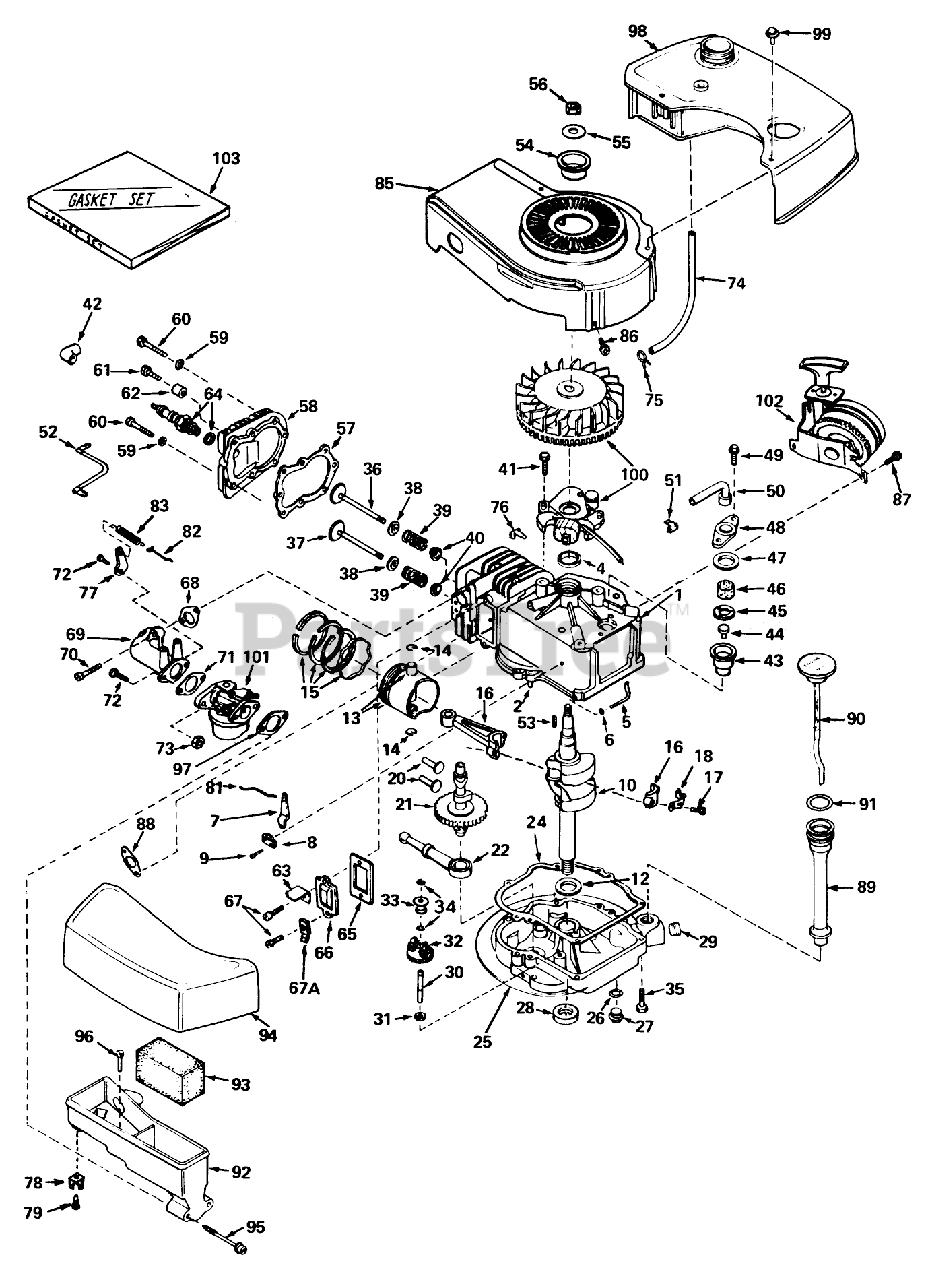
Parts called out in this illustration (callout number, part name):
1	Cylinder Assembly (Incl. Nos. 2, 4 87)
2	Pin-Dowel
4	Seal-Oil
5	Rod, Governor (Incl. No. 36)
6	Washer-Flat
7	Governor Lever
8	Clamp-Lever, Governor
9	Screw
10	Crankshaft
12	Washer-Thrust
13	Piston Pin Assembly (Incl. 2 of No. 14)(Std.)
13	Piston Pin Assembly (Incl. 2 of No. 14)(.010 Oversize)
13	Piston Pin Assembly (Incl. 2 of No. 14)(.020 Oversize)
14	Ring-Retaining, Piston Pin
15	Ring Set-Piston Std.
15	Ring Set-Piston .010 oversize
15	Ring Set-Piston .020 oversize
16	Rod Assembly, Connecting (Incl. Nos. 17 18)
17	Connecting Rod Bolt
18	Plate Lock
20	Lifter-Valve
21	Camshaft(Mech.Comp. Release)
22	Oil Pump ASM
24	Gasket, Mounting
25	Flange Assembly, Mounting (Incl. #27, 28, 29 30)
26	Gasket-Oil Drain
27	Plug Oil Drain
28	Seal-Oil
29	Plug Oil Drain
30	Shaft-Governor
31	Washer-Flat
32	Gear Assembly, Governor
33	Spool, Governor
34	Ring-Retaining
35	Screw (1/4-20 x 1-1/4)
36	Valve, Intake (Incl. Ref. #38, 39 40) (Std.)
36	Valve, Exhaust (1/32" Oversize) (Incl. Nos. 8, 9 10)
37	Valve, Exhaust (Standard) (Incl. Nos. 8, 9 10)
37	Valve, Exhaust (1/32" Oversize) (Incl. Nos. 8, 9 10)
38	Cap-Upper Valve Spring
39	Spring-Valve
40	Cap-Valve, Spring
41	Screw
42	Cover-Spark Plug
43	Body Breather Tube
44	Valve Check
45	2000A37 WIZARD ROTA
46	Element-Breather
47	Gasket-Breather
48	Cover Breather
49	Screw, Hex Hd. w/Conical
50	Tube, Breaker
51	Clip, Breather
52	Wire, Ground
53	Key Flywheel
55	Washer
56	Hex Nut
57	Oil Fill Tube
58	Head Cylinder
59	Washer
60	Screw
61	Screw Hex Hd. Cap
62	Space
63	Retainer Clip
64	Plug, Spark (J17LM or equiv.)
65	Gasket-Breather
66	Cover-Valve
67	Screw
67A	Terminal
68	Gasket, Intake
69	Pipe, Intake
70	Screw (1/4-20 x 1)
71	Gasket-Carburetor
73	Nut and Lock Washer (1/4-28)
74	Line, Fuel
75	Clamp-Line, Fuel
76	Clip-Wire
77	Lever-Adjusting, R P M
78	Terminal
79	Screw (8-32 x 3/8)
81	Link Governor
82	Link Governor Spring
83	Spring Governor
85	Housing, Blower
86	Screw
87	Screw (1/4-20 x 1/2)
88	Gasket Exhaust
89	Tube, Oil Filler
90	Dipstick, OiI (Incl. No. 91)
91	O-Ring
92	Body Air Cleaner
93	Filer, Air
94	Cove, Air Cleaner
95	Screw Fil Hd.
96	Screw, Hex Hd.
97	Gasket-Air Cleaner
98	Tank Fuel
99	Screw (10-32 x 35/64)
100	LEVER
101	Carburetor
102	Starter, Side Mount
103	53024/VAR.16HP O/P
